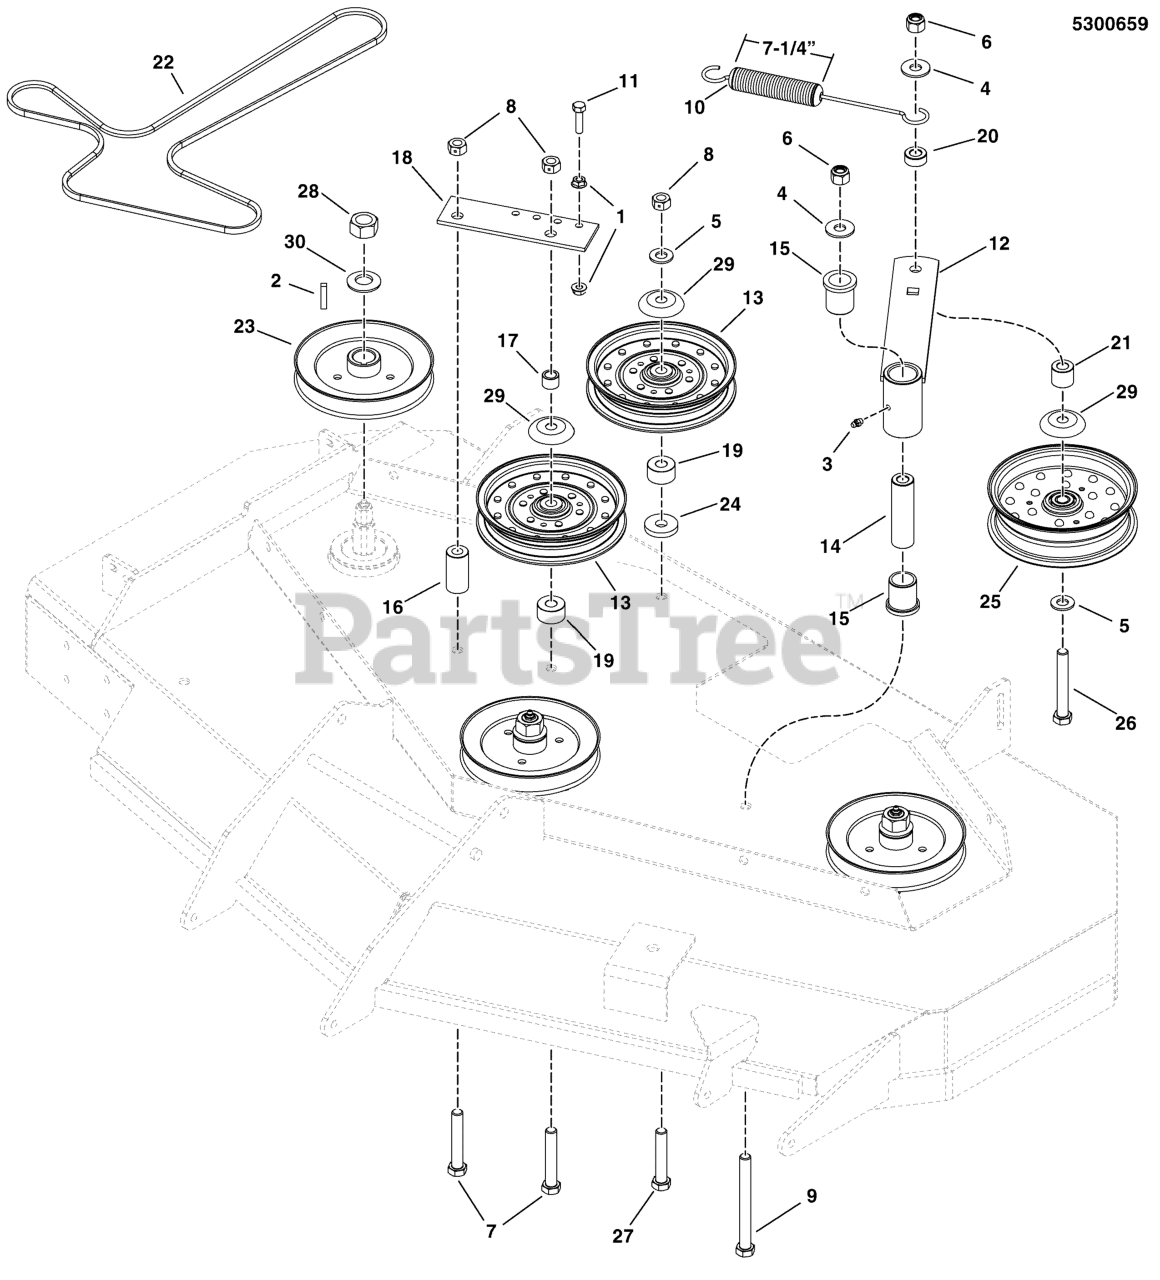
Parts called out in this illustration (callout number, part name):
1	NUT, 5/16-18 HEX SERRATED FLANGE (SMALL)
2	KEY, 1/4" SQ. X 1-1/4
3	GREASE FITTING, 1/4-28 Straight
4	WASHER, 1/2" USSZ
5	WASHER, 1/2 SAE
6	NUT, 1/2-13 HEX NYLON LOCK
7	BOLT, 1/2-13 X 3" GD5 CZ
8	NUT, 1/2-13 Hex Side Lock
9	BOLT, 1/2-13 X 5" GD5 YZ
10	SPRING-EXT, 1.04 ODX10.535LGX.148WR, BLK
11	BOLT, 5/16-18 X 1-1/4" GD5 YZ
12	ASSM, IDLER ARM
14	SPACER, .52 x 1.00 x 3.50
15	BUSHING, FLANGE
16	SPACER, .50 X 1.00 X 2.00
17	SPACER, .51 X .75 X .56, PM, CZ
18	PLATE, SPRING ANCHOR - RED
19	SPACER, .52 X 1.25 X .70, PM, CZ
20	SPACER, .52 X 1.00 X .44, CZ
21	SPACER, .52 X 1.00 X .88, PM, CZ
22	BELT, 5V, 160.60"EL, LRG ARAMID, WRP, RC
23	PULLEY, 5.926OB X .985ID, SINGLE B-SEC
24	WASHER, .53 X 1.50 X .25
25	PULLEY, IDLER, 6.75 OD X 1.62 FACE
26	BOLT, 1/2-13 X 3-1/2, HEX HD, GD5, CZ (SV)
27	BOLT, 1/2-13 X 2-3/4 GD5 CZ
28	NUT, 3/4-16 Hex
29	SHIELD, PULLEY BEARING, CZ
30	WASHER, 3/4 BELLEVILLE CL/ZC
